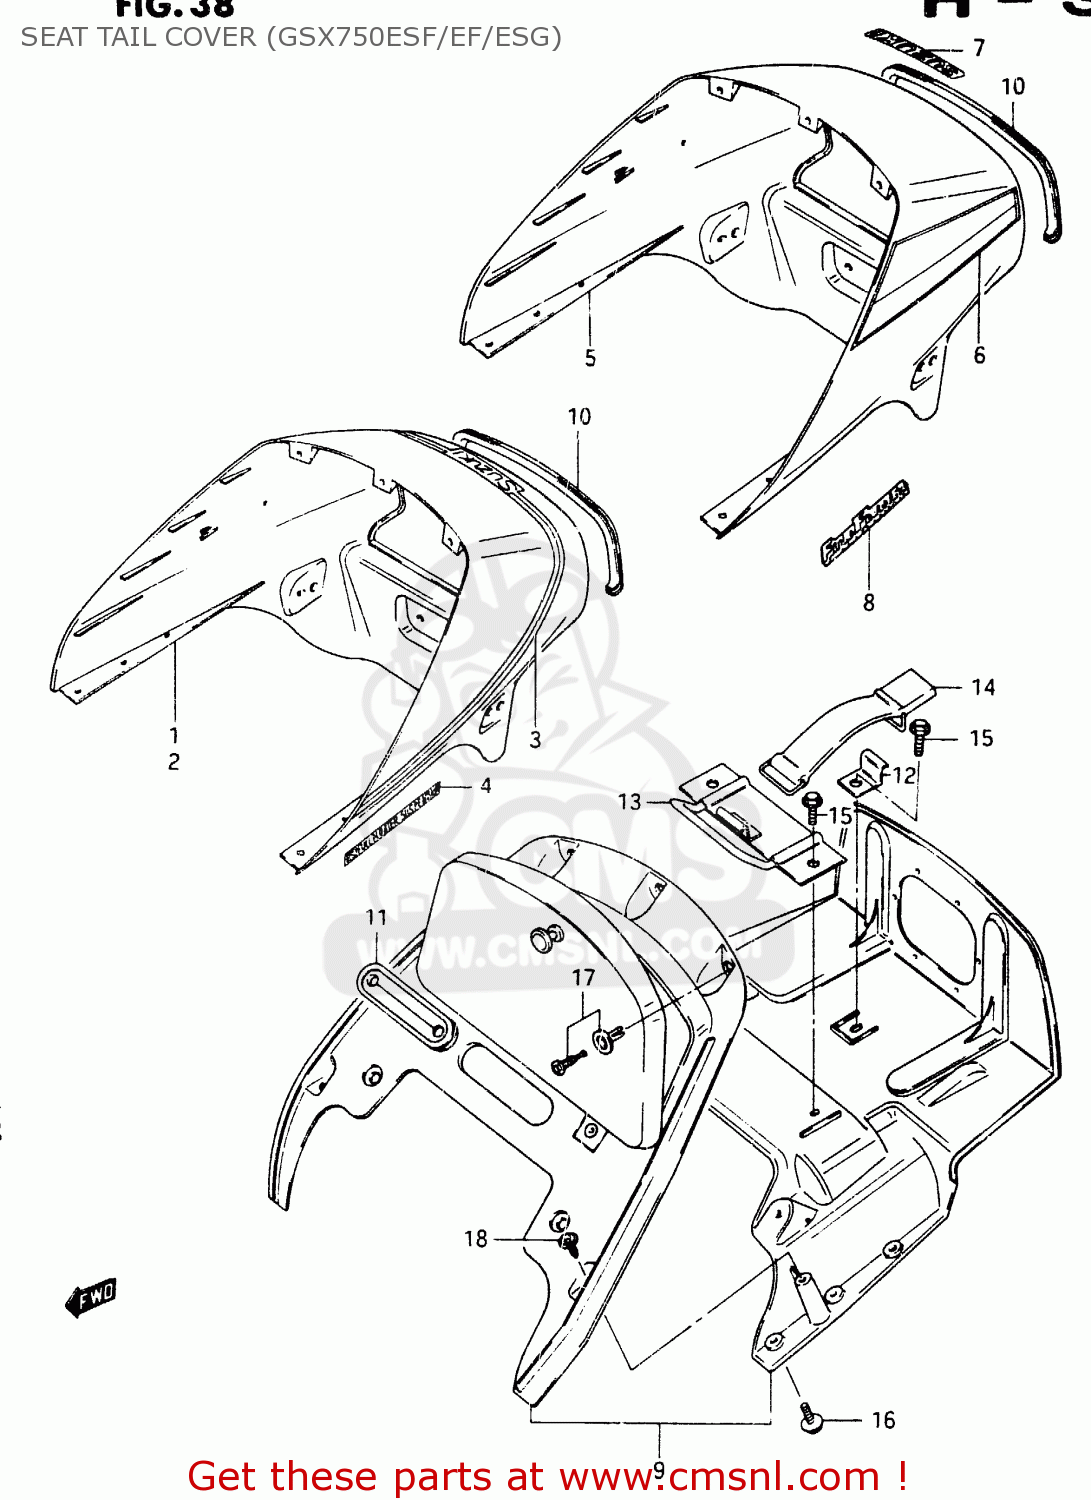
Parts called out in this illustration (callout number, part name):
1	TAIL COVER, SEAT
2	TAIL COVER, SEAT
3	TAPE SET, SEAT TAIL COVER
4	EMBLEM
5	SEAT TAIL COVE
6	TAPE SET, SEAT TAIL COVER
7	EMBLEM
8	EMBLEM
9	FLAP,SEAT TAIL COVER
10	MOLDING,SEAT TAIL COVER
11	GROMMET,SEAT TAIL COVER
12	PLATE,CHAIN LOCK HOLDER
13	PLATE,SEAT HOOK
14	BAND
15	BOLT
16	SCREW
17	CLIP
18	SCREW
